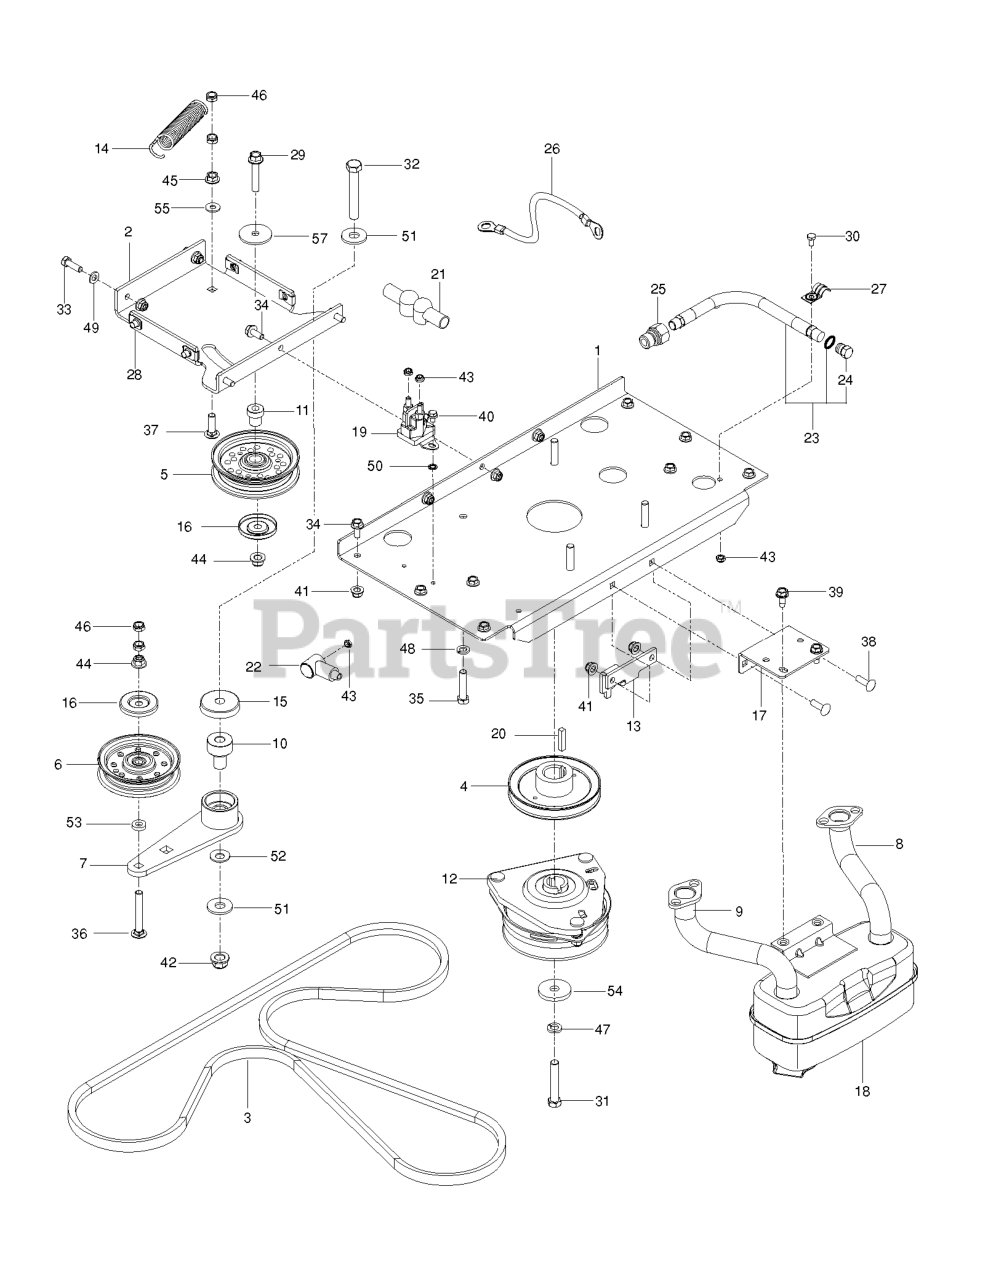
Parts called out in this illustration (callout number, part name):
1	PLATE.PNT.ENGINE.E-DIP
2	PLATE.PNT.IDLER.SUPPORT.E-DIP
3	BELT, HYDRO, 3400
4	PULLEY.DRIVE.XMSN
5	IDLER PULLEY
6	PULLEY.IDLER.FLAT.46.PR.DR.
7	ARM, IDLER, STEEL, W/BGS
8	TUBE.EXHAUST.RH.FR961/FR730
9	TUBE.EXHAUST.LH.FR961/FR730
10	PIVOT, BEARING
11	PIVOT, IDLER
12	CLUTCH MZ ZTR GT.48/54"1.125"
13	BRACKET.CLUTCH.STOP.PNTX431
14	SPRING, PUMP
15	SHIELD, DUST
16	DUST SHIELD
17	BRKT, MUFFLER, BLK
18	MUFFLER ASM TWIN
19	SOLENOID.W/BRASS.PLUNGER
20	KEY, 1/4 SQ X 1 1/4
22	TERMINAL COVER
23	HOSE.ASSEMBLY.OIL.DRAIN
24	PLUG OIL DRAIN
25	ADAPTER, OIL DRAIN
26	CABLE POSITIVE
28	U-CLIP 5/16-18 NUT RETAINER
29	HHFS 3/8-16 X 2.0 GD 5
30	HCS 1/4-20.
31	CLUTCH BOLT7/16-20X2.5 GR596HR
32	HCS 1/2C X 3 1/4
33	HCS 5/16C X 1
34	HHFS 5/16-18 X 3/4
35	HCS 3/8-16X1.GRD.5.ZD
36	RHSNB 3/8-16 X 2.75
37	RHSNB 3/8-16 X 1-1/4
38	RHSSNB 5/16C X 1.0
39	BOLT 5/16-18 X 3/4
40	HWST 1/4C X 3/8
41	5/16-18 NYLOC FLANGE NUT
42	NUT, 1/2-13 HEX FLG NYLOC ZD
43	JAM NUT 1/4C (2 2 PW01)
44	NUT 3/8-16 HEX FLG NYLOC ZD
45	NUT 3/8C WHIZ
46	NUT HEX 3/8-16 NYLON, THIN
47	SLW 3/8 STD
48	WASHER 7/16 LOCK
49	FLAT WASHER 5/16 SAE
50	WASHER 1/4 INT TOOTH
51	WASH USS FLAT 1/2
52	CONTACT BELLSPR 1/2
53	WASHER 3/8 X 3/4 X .187 TK
54	SPINDLE WASHER
55	RP WASHER 3/8 FLAT
56	WASHER, 3/8 SPEC
